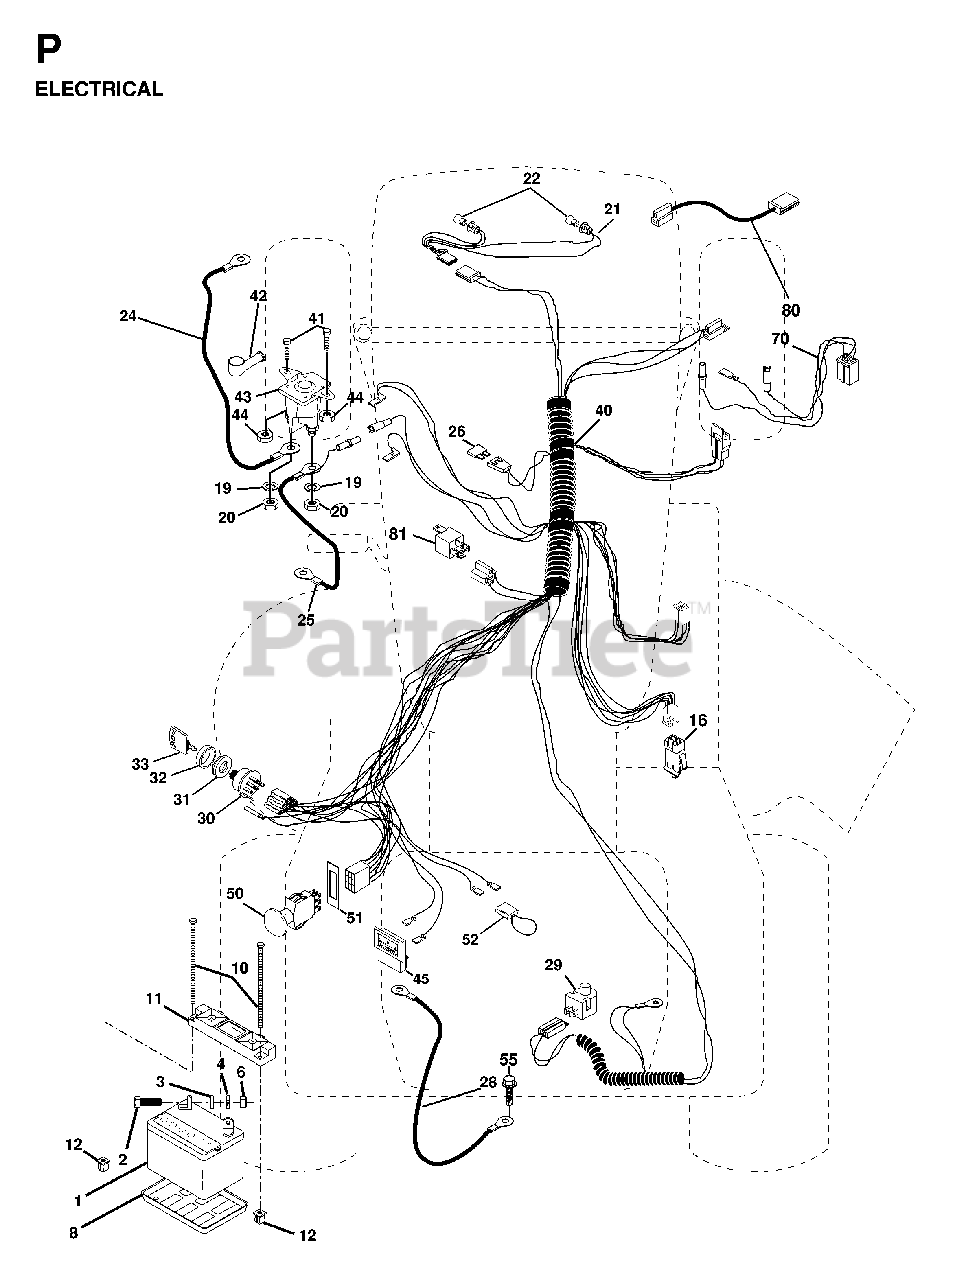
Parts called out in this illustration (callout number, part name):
1	REPL BY 532 12 38-99
3	WASHER
4	LOCKWASHER
6	NUT
8	BATTERY TRAY T
10	BOLT 1/4-20 X 7.5
11	BATTERY HOLDDOWN
12	NUT, PUSH NYLON 1/4" BATTERY
16	SWITCH INTERLOCK
19	LOCKWASHER
20	NUT
21	HARNESS ASM HDLIG
22	LIGHTBULB
24	BATTERY CABLE GT
25	CABLE BATTERY 6 GA 22" W/16W
28	CABLE GROUND 6 GA 21" 90T BLK
29	PLUNGER SWITCH (COLOR:OLIVE)
30	SWITCH.IGNITION.4.POSITION
31	NUT IGNITION
32	COVER SWITCH KEY
40	HARNESS.IGNITION
42	TERMINAL COVER
43	SOLINOID
50	SWITCH PTO 3 PDT
51	RETAINING RING
52	WIRE PROTECTION LOOP
80	HARNESS, CLUTCH
81	RELAY.ASSY.T
